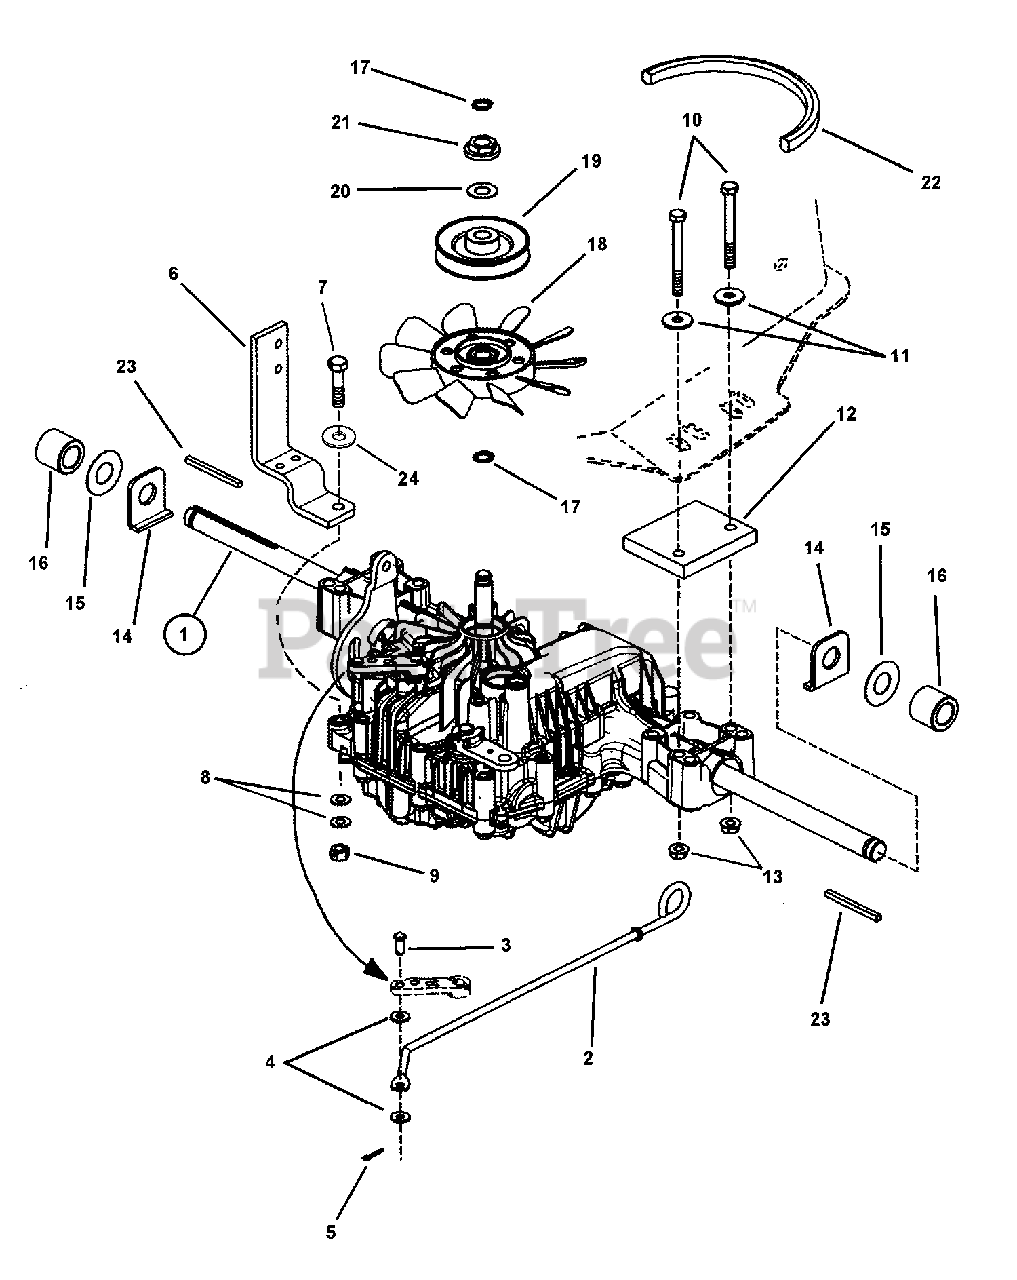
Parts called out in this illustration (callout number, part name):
1	ASSEMBLY, Transaxle-Tuff Torq, hand control K46 Hydro
2	ROD, Roll Release- K46
3	PIN, 1/4 x 5/8" Clevis
4	WASHER, 1/4 x 5/8 x 1/16" Flat
5	PIN, 3/32 x 1/2" Cotter
6	BRACKET, Torque/Spool- TTK46
7	SCREW, 5/16-18 x 2" Hex Head Cap, GR5
8	WASHER, 5/16 x 11/16 x 1/16" Flat, GR5
9	NUT, 5/16-18-3B Hex Nyloc
10	SCREW, 5/16-18 x 3" Hex Head Cap, GR5
11	WASHER, .34 x 1.0 x .09 Flat
12	SPACER, Hydro Axle- Steel- K46
13	NUT, 5/16-18 Hex Flange Lock, GR5
14	WASHER, Axle- TT K46 Hydro
15	THRUST WASHER
16	SPACER, Axle- K46
17	SNAP RING, Special (Kanzaki # 192154-89090) 1
18	FAN (Vendor # 1A640-83050)
19	PULLEY, 4" Diameter (Vendor # 1A6460-25333)
20	WASHER, Wave (Vendor # 1A6460-83060)
21	SPACER (Vendor # 1A6460-25300)
22	BELT, Traction Drive (HA Section, 96.60" effective length)
23	KEY, 3/16" Square x 2-3/16" long
24	WASHER, 5/16" Internal Tooth Lock
